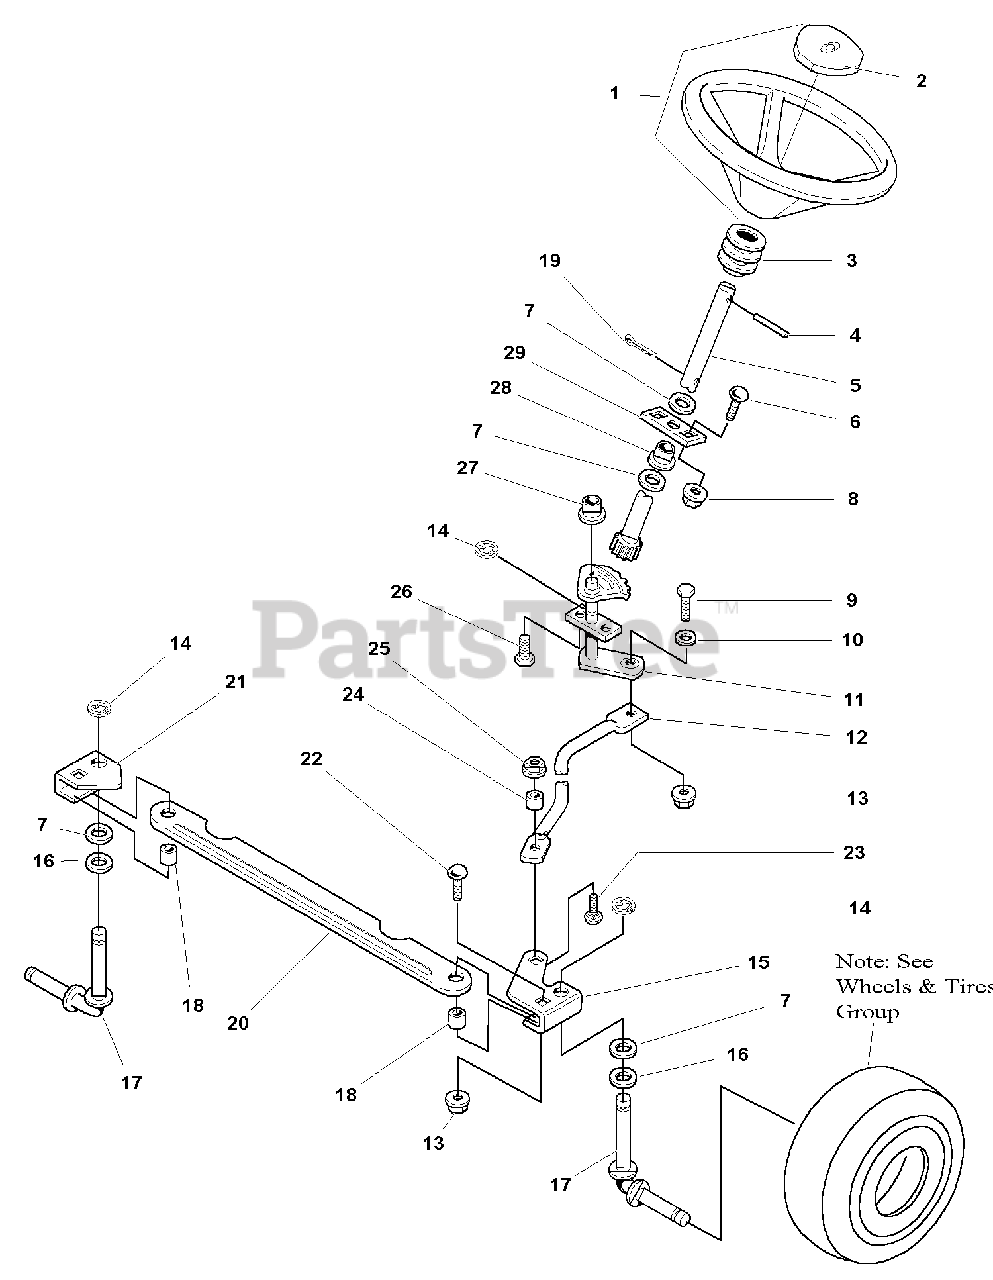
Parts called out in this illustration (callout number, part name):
1	STEERING WHEEL ASSEMBLY, (Includes Ref. No. 2)
2	CAP, Steering Wheel
4	PIN, Spring, 5/16 x 2-1/2
5	SHAFT ASSEMBLY, Steering
6	CARRIAGE BOLT, 3/8-16 x 1
7	WASHER, 3/4
8	NUT, Hex Flange Whiz Lock, 3/8-16
9	CAPSCREW, Hex Head 3/8-16 x 1-1/4
10	WASHER, 3/8
11	STEERING GEAR ASSEMBLY
13	NUT, Hex Flange Lock, 3/8-16
15	ARM, Steering, LH
16	WASHER, 3/4
17	SPINDLE ASSEMBLY
19	PIN, Cotter, 3/16 x 1-1/4
21	ARM, Steering, RH
22	CARRIAGE BOLT, 3/8-16 x 1-1/4
23	CARRIAGE BOLT, 5/16-18 x 1
25	NUT, Hex Flange Lock, 5/16-18
26	CAPSCREW, Taptite Hex Washer Head, 5/16-18 x 3/4
29	PLATE, Steering, Mounting
